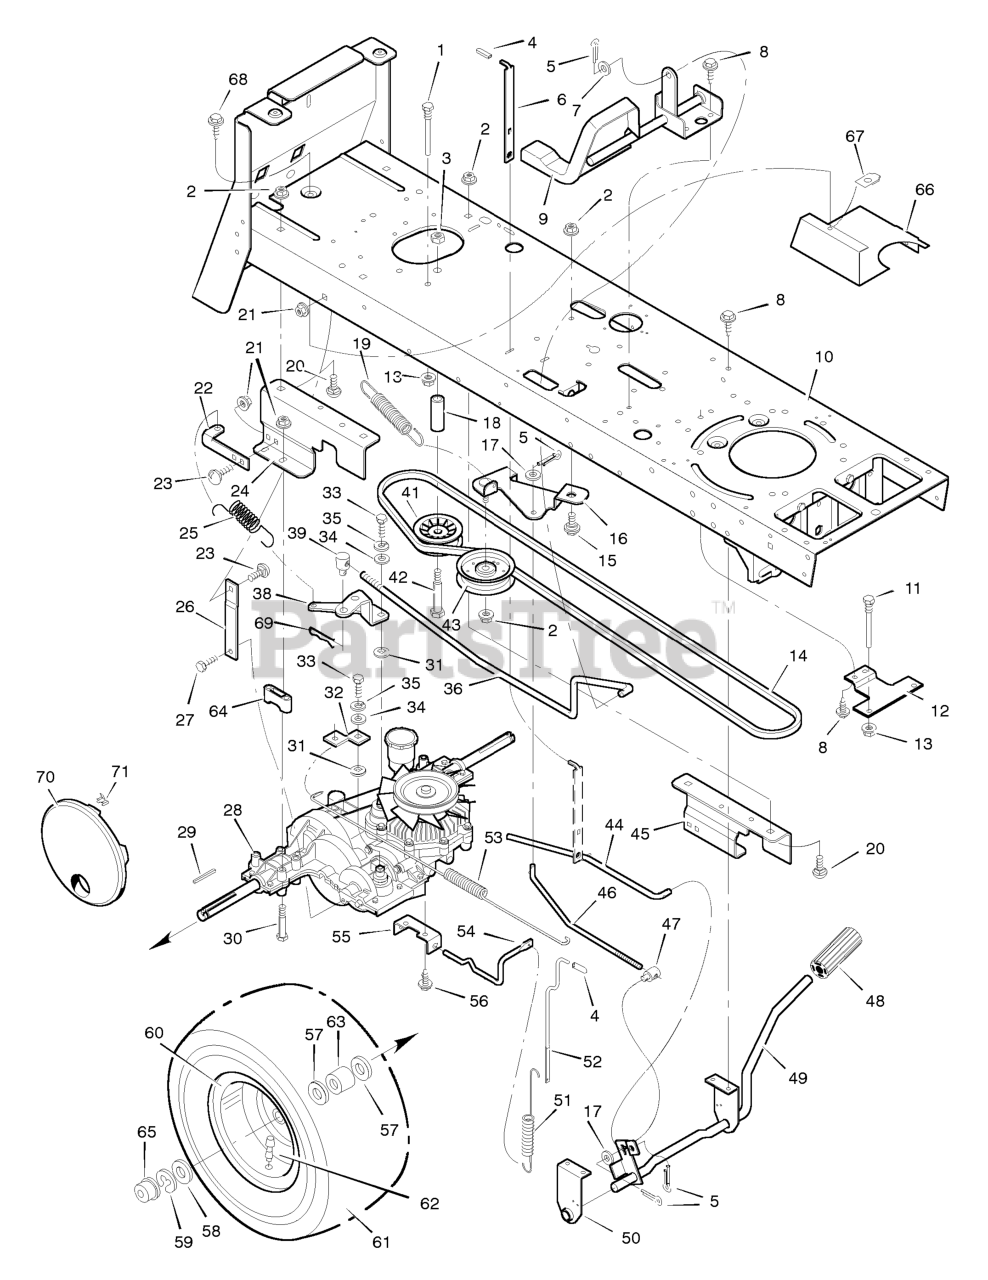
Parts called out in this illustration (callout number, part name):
1	Guide, Belt
2	Nut, Flange
3	Nut, Hex
5	Pin, Hair
6	Lever, Parking Brake
9	Pedal Assembly
10	Frame Assembly
11	Guide, Belt
12	Bracket, Belt Guide
13	Nut, Flange
15	Bolt, Shoulder
16	Bracket, Idler
17	Washer
18	Spacer
20	Bolt, Carriage
21	Nut, Flange
22	Bracket, Spring
23	Bolt, Carriage
24	Bracket, Right Transaxle
26	Bracket, Torque
28	Transaxle **
29	Key, Square
32	Yoke, Brake
35	Lockwasher
36	Rod, Control
38	Lever, Control
39	NUT, Adjusting, 1/2-13
41	Pulley, Idler
43	Pulley, Idler
44	Rod, Latch
45	Bracket, Left Transaxle
46	Rod, Clutch
47	Nut, Adjusting
48	Pedal
49	Lever Assembly, Pedal
50	Pedal Assembly
51	Spring, Extension
52	Rod, Dump Valve
53	Spring, Extension
54	Rod, Dump Valve
55	Bracket, Dump Valve
60	Wheel and Tire Assembly
61	Tire *
62	Valve Stem
63	Spacer, Wheel
64	Spacer, Transaxle
65	Hub Cap
66	Air Baffle, Hydro
67	Nut, Speed
68	Screw
69	Pin, Hair
70	Disc, Wheel
71	Clip, Retainer
